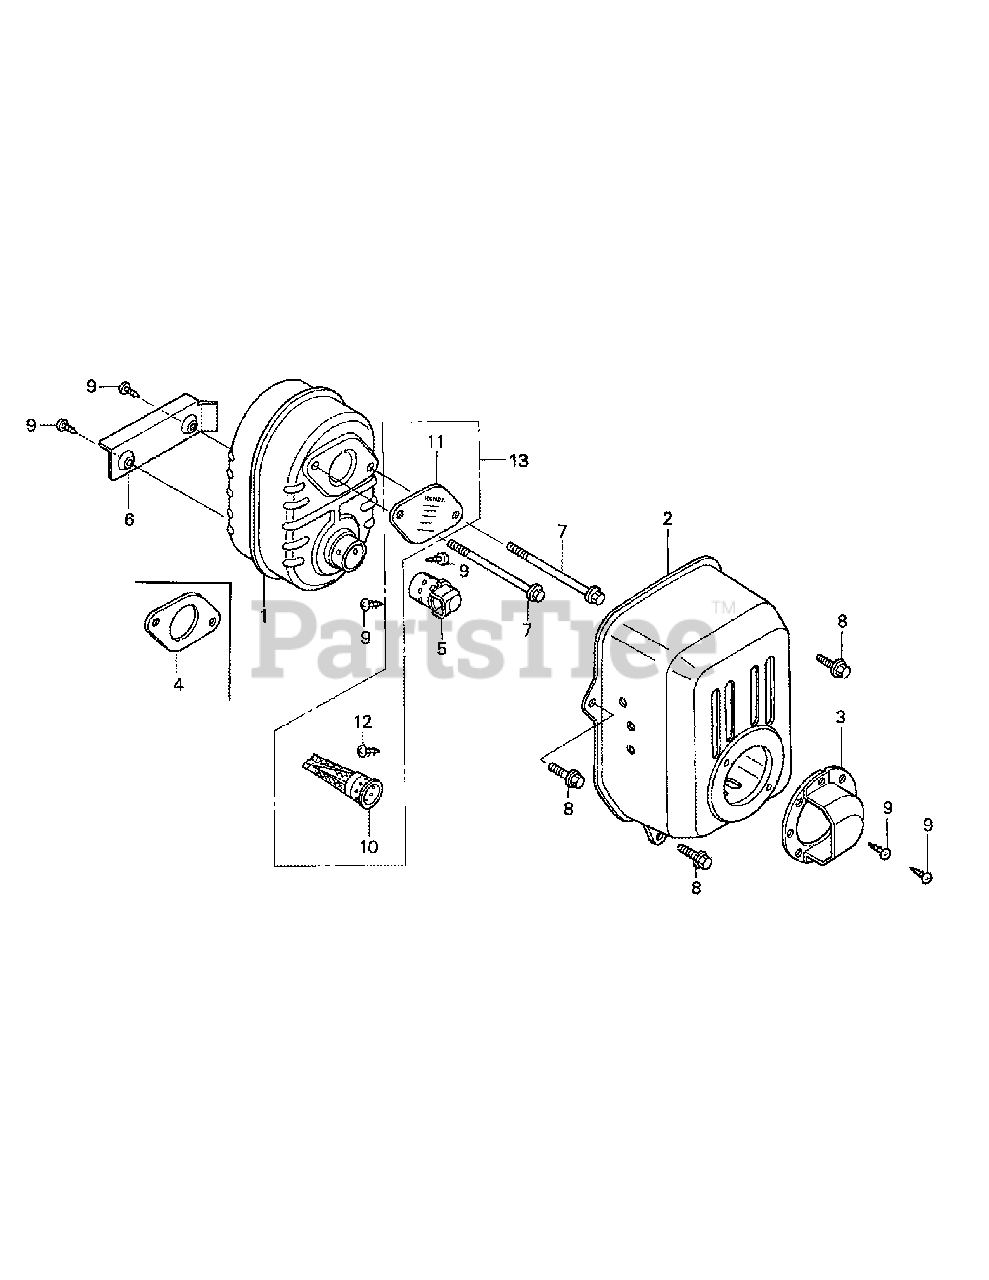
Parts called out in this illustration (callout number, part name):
1	Muffler
2	Muffler Protector
4	Muffler Gasket
7	Flange Bolt, 6 x 79
8	Flange Bolt, 6 x 12
10	Spark Arrester
11	Arrester Number Plate
12	Tapping Screw, 4 x 6
13	Spark Arrester Kit
